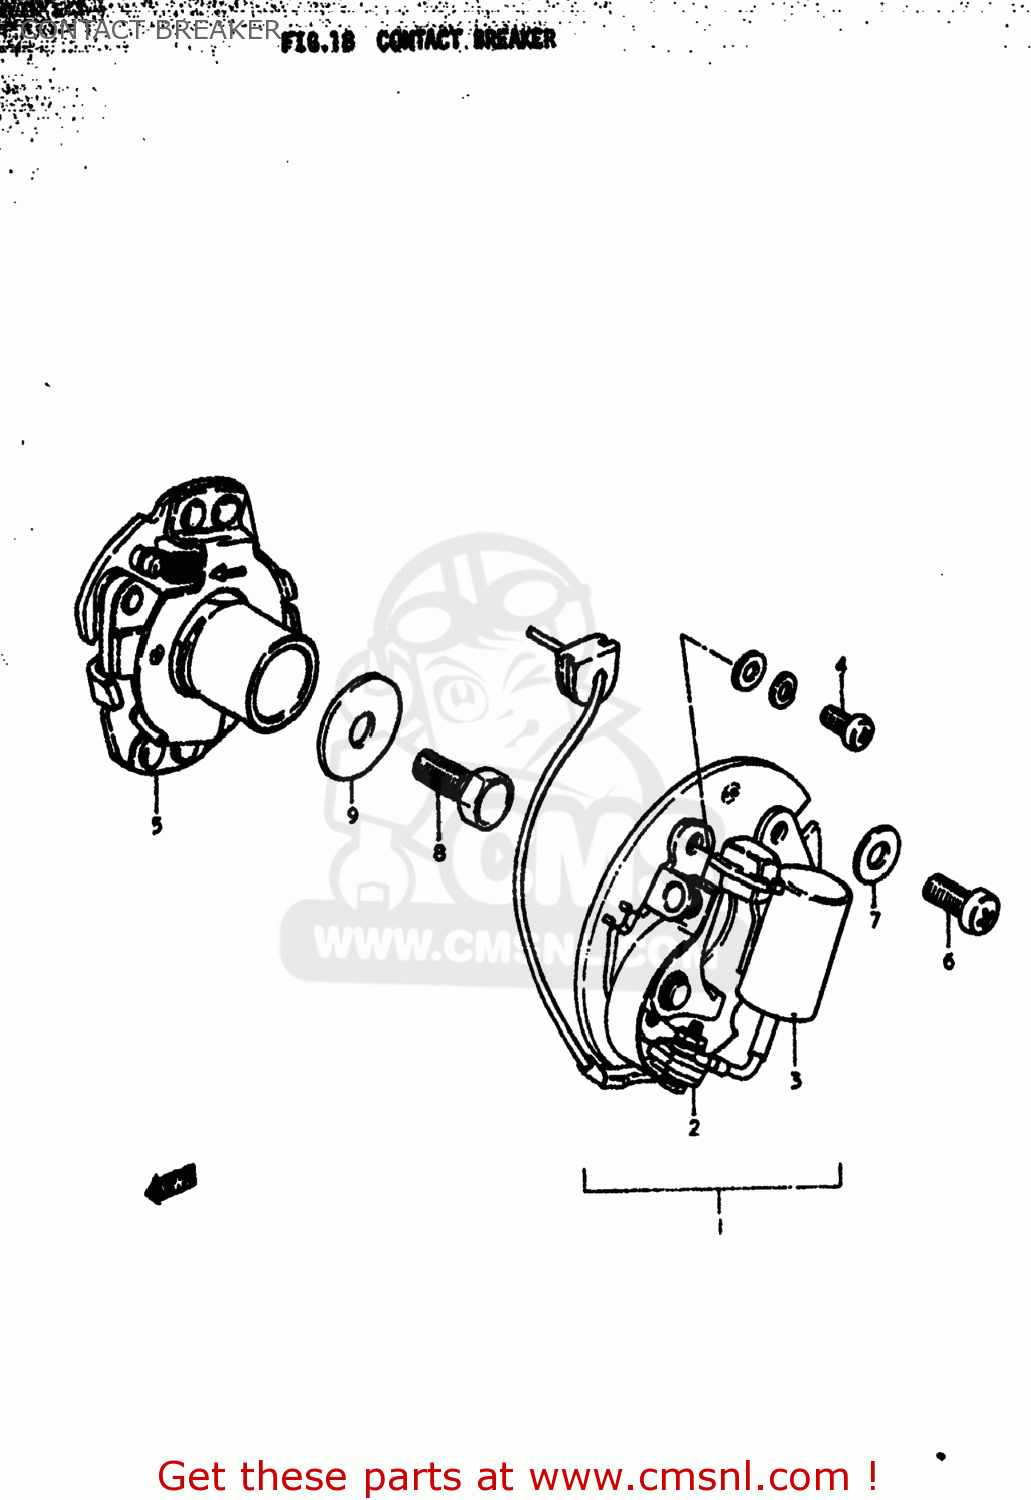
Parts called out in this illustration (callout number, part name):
1	STATOR,SIGNAL GENERATOR
2	POINT ASSY,CONTACT
3	CONDENSER
4	SCREW
5	GOVERNOR ASSEMBLY
6	SCREW(5X12)
7	WASHER
8	BOLT, UPPER
9	WASHER (6X20X1.5)
